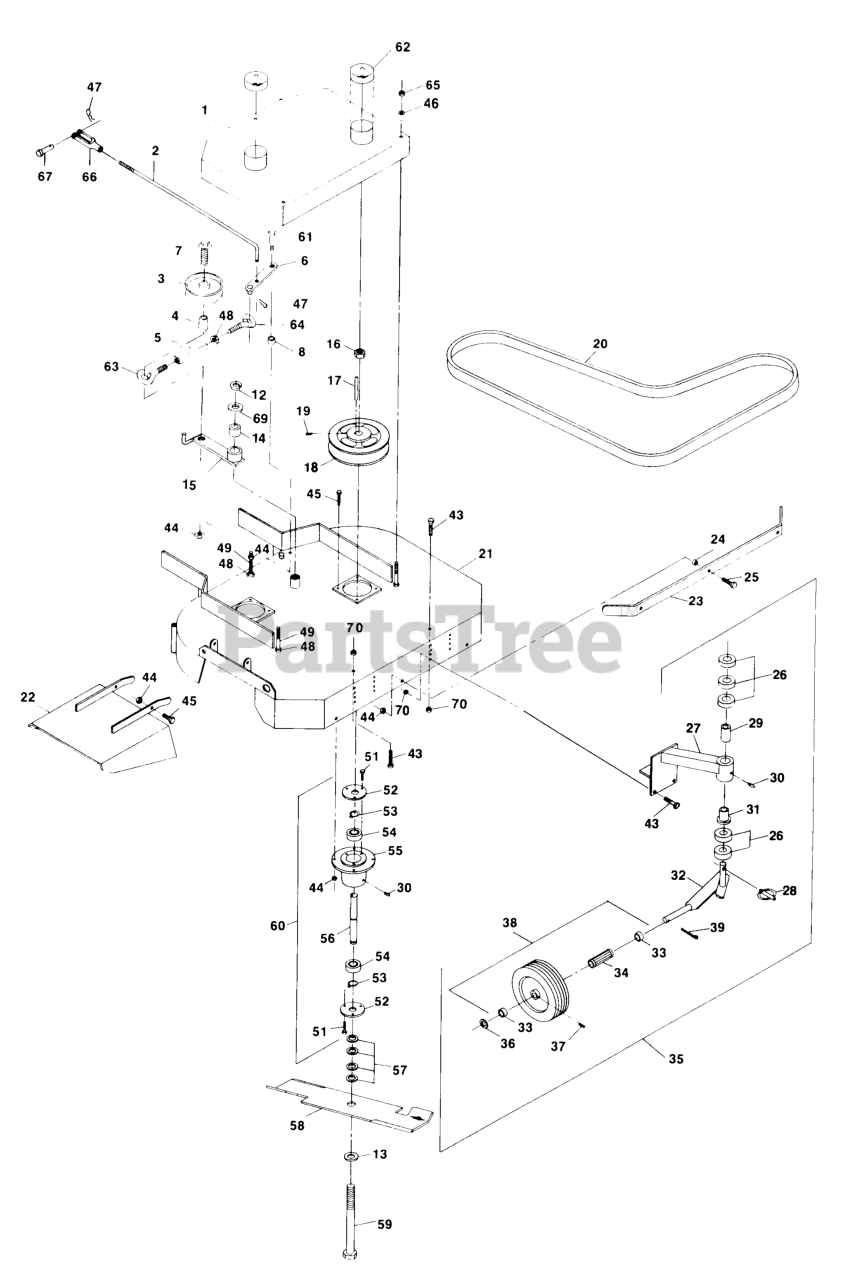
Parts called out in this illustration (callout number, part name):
5	BODY-TURNBUCKLE
14	BEARING,POWDERED METAL
18	PULLEY,CAST IRON
19	SCREW-SET
20	BELT,BLADE DRIVE
26	SPACER-CASTER
29	BEARING,STRAIGHT
32	WLD,STRUT CASTER
47	PIN-COTTER
49	BOLT,TAP HH
51	SCRWMACH PHS
55	HOUSING,CUTTER
56	SPINDLE,CUTTER
60	HOUSING,CUTTER COMPLETE
61	BOLT,SHLDR KSKH
62	CAP,SPINDLE GUARD
63	EYEBOLT-THREAD, LH
64	EYEBOLT-THREAD, RH
66	YOKE-ADJUSTABLE
67	PIN-CLEVIS
69	WASHER-SPINDLE
